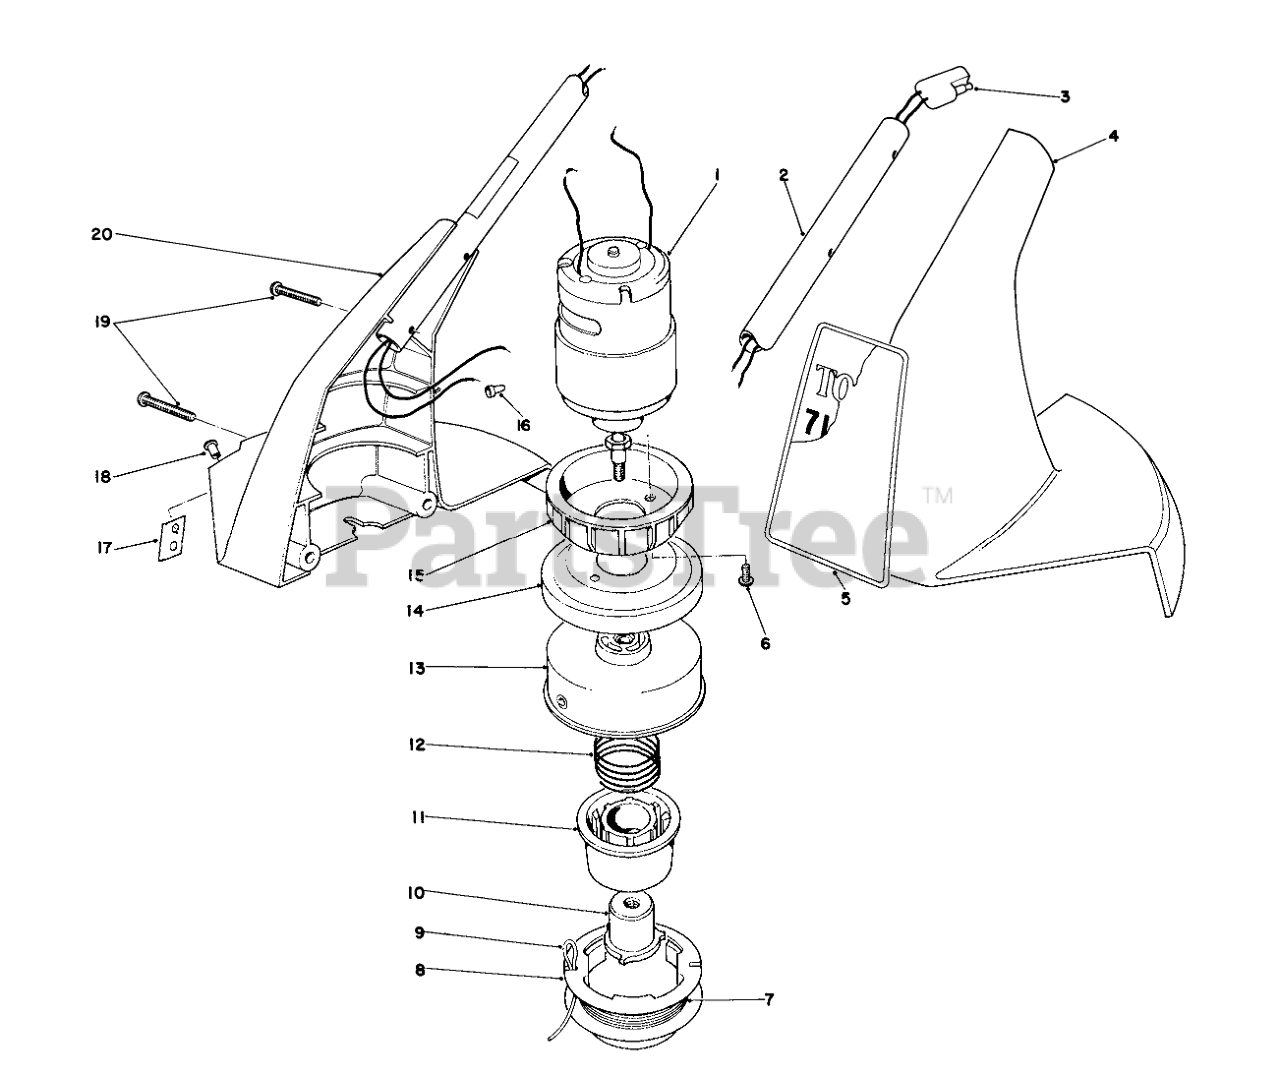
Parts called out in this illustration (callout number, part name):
1	MOTOR ASM
2	EXTENSION HANDLE
3	WIRING HARNESS LOWER
4	Housing-Motor L.H.
5	710 HOUSING DECAL
6	SCREW
7	Prewound Spool
8	CAP-SPOOL
9	Line-Cutting (30- .05 Dia.)
10	DRIVER
11	CORE - SPOOL
12	Spring
13	Drum w/Eyelet
14	DRUM CUP
15	Casting-Heat Sink
16	Connector
17	Blade-Knife
18	Rivet
19	SCREW-PLASTITE
20	Housing-R.H. Motor (Incl. Ref. #17 & 18)
